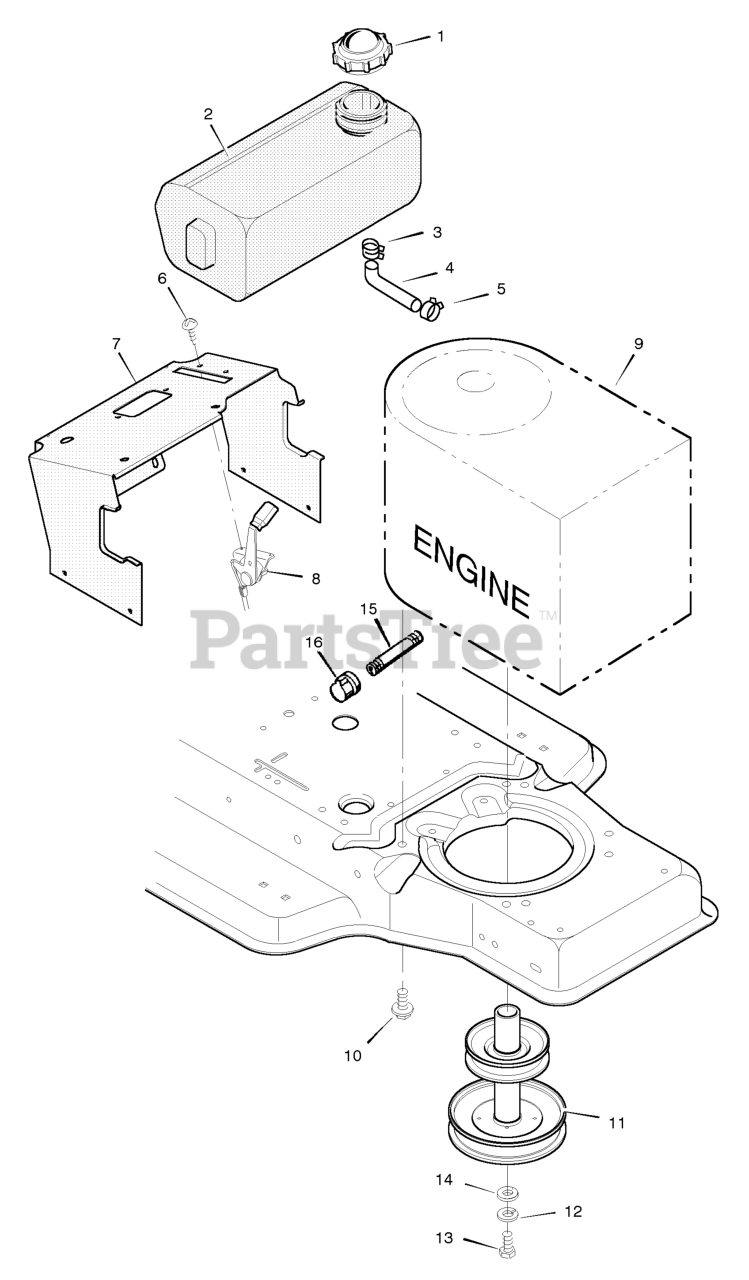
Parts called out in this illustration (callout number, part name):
1	Fuel Cap
2	Fuel Tank
3	Hose Clamp
4	Fuel Line
5	Hose Clamp
7	Support, Dash
8	Throttle Control
9	Engine *
10	Bolt, Engine Mount
11	Stack Pulley Assembly
12	Lockwasher
13	Bolt, Hex
15	Pipe, Oil Drain
16	Cap, Oil Drain
